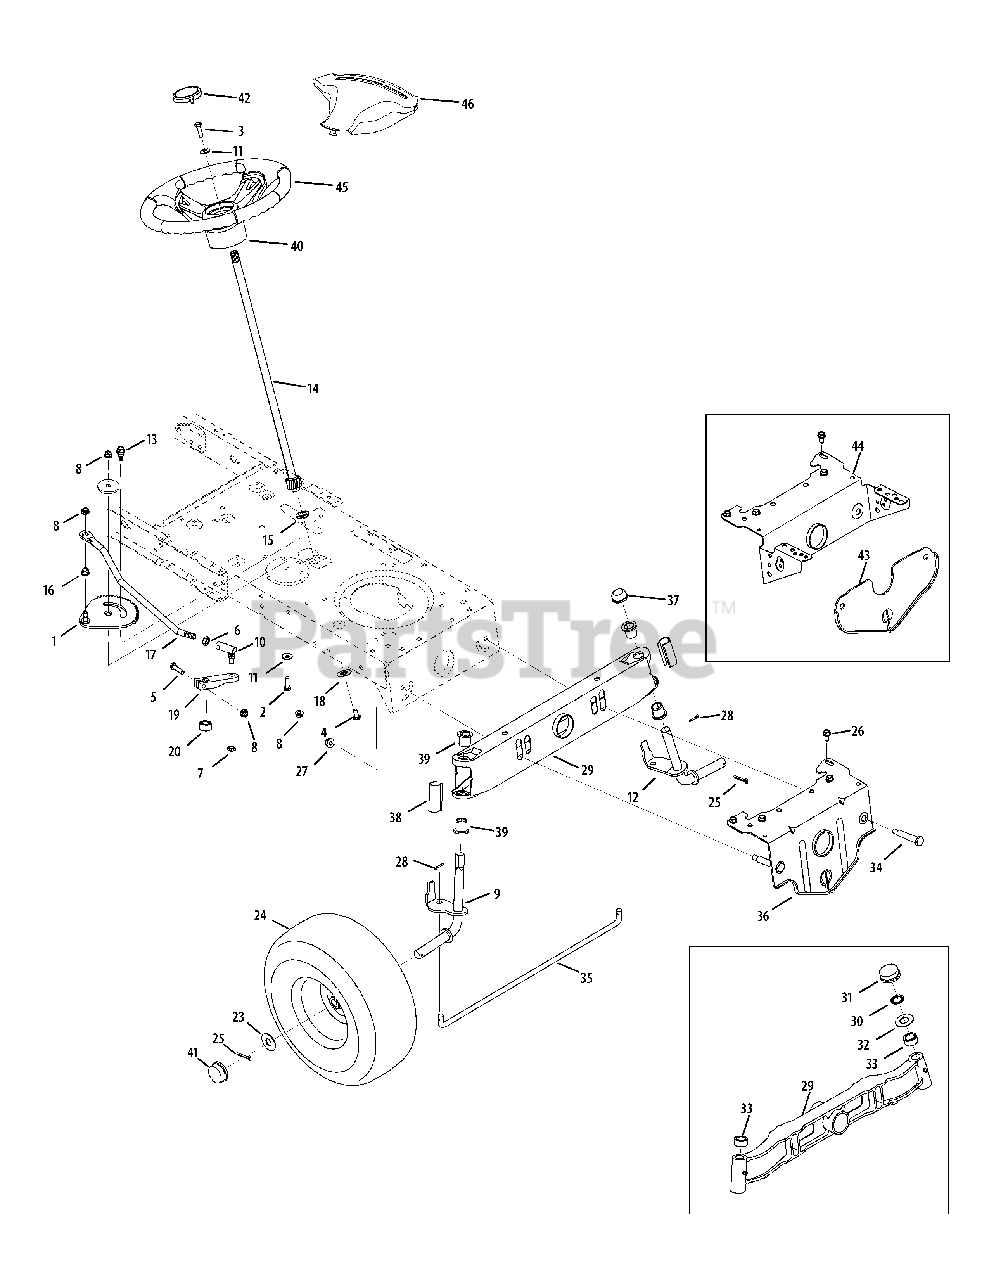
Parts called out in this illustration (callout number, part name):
1	Steering Gear Assembly
2	Hex Hd. Cap Screw 3/8-16 x 1,00 Gr. 5
3	Hex Screw 5/16-18 x 1.00 Special
4	Machine Screw 5/16-18 x .75
5	Hex Screw 5/16-18 x 1.75" Lg.
6	Hex Jam Nut 7/16-20
7	Hex Cent-L Nut 3/8-24 Gr. B
8	Flange Locknut 5/16-18 Gr. F, Nylon
9	Axle Assembly, RH
9	Axle Assembly, RH (w/46" deck)
10	Ball Joint, 7/16 - 20
11	Cupped Washer .345 ID x .88 OD x .060
12	Axle Assembly, LH
12	Axle Assembly, LH (w/46" deck)
13	Shoulder Screw .435 x .3485, 5/16-18
14	Steering Shaft, 5/8 Spline x 21.86
15	Hex Flange Bearing 5/8
16	Plastic Bushing .375 ID x .5
17	Steering Drag Link
18	Cap, 1.25 x .16
19	Steering Block
20	Spacer .710 ID x .125 OD x .56
22	Shoulder Spacer
23	Flat Washer .781 ID x 1.59 OD Special
25	Cotter Pin 5/32 x 1.25
26	S-Tapp Screw 5/16-18 x .75
27	Flange Lock-Nut 3/8-16 Gr. F, Nylon
28	Cotter Pin 1/8" Dia x .75
29	Pivot Bar (cast iron)
30	Push Nut 3/4"
31	Axle End Cap
32	Flat Washer .78 x 1.59 x .060
33	Spacer .71 x .125 x .56
34	Shoulder Screw .500 x 2.380, 3/8-16
35	Tie Rod
36	Pivot Bar Bracket
37	Push Cap, .750
38	Axle End Cap, Standard
39	Flange Bearing .760 ID x .937 OD
40	Steering Wheel, Standard Grip
41	Plastic Hub Cap
42	Steering Wheel Cap (w/o logo)
42	Steering Wheel Cap (sprig logo)
45	Steering Wheel
45	Steering Wheel, Soft Grip
46	Steering Wheel Cover (MTD)
